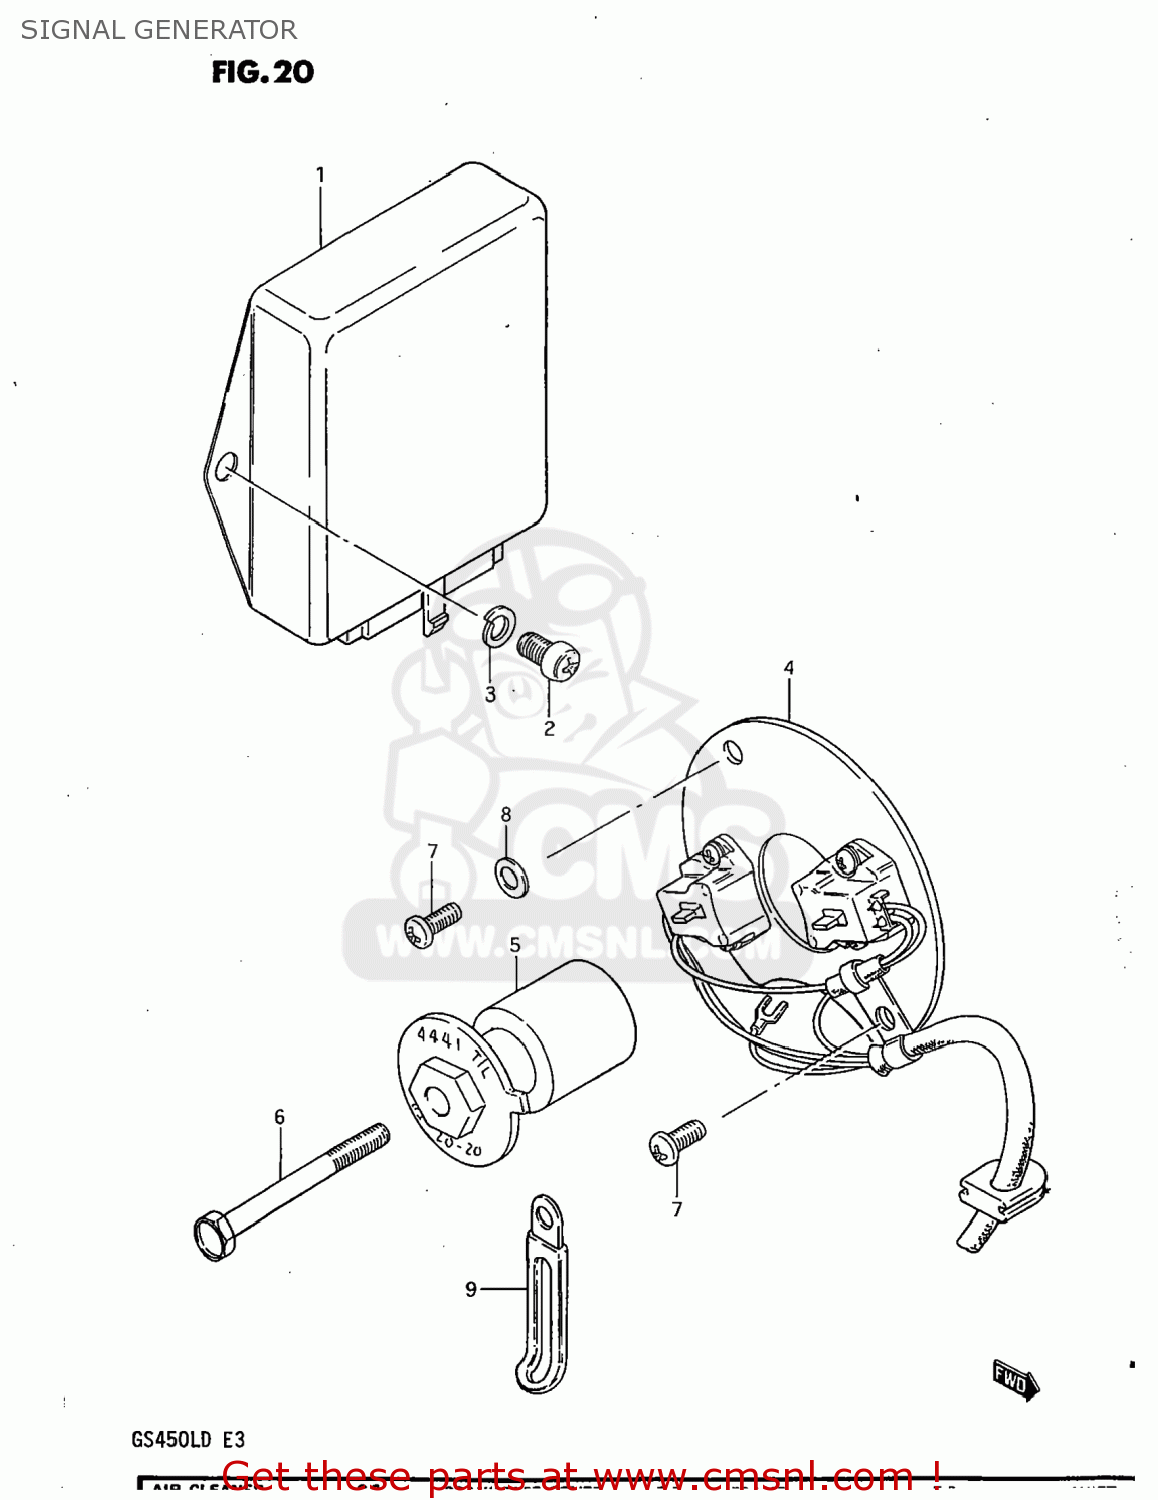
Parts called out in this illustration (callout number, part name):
1	IGNITOR UNIT
2	SCREW
3	LOCK WASHER
4	SIGNAL GENERATOR ASSEMBLY
5	ROTOR,SIGNAL
6	BOLT 6X60
7	SCREW(5X12)
8	WASHER
9	CLAMP L:35
